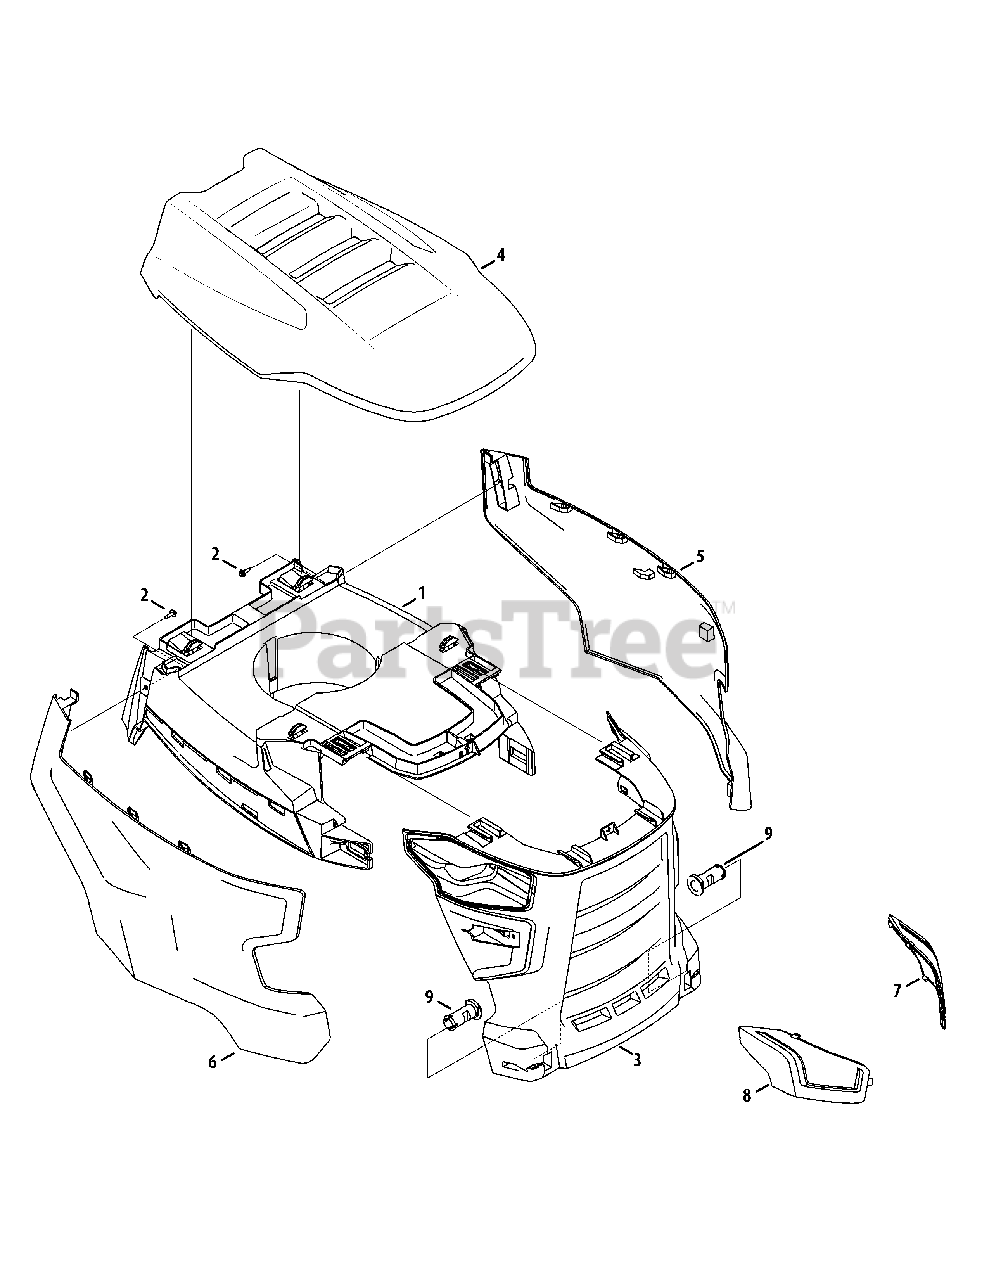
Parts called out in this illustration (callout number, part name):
1	Hood Frame
2	Screw, 1/4-10 x .75
3	Grill
4	Hood, Top
5	Hood, Side, LH
6	Hood, Side, RH
7	Headlight Lens, LH
8	Headlight Lens, RH
9	Hood Pin
